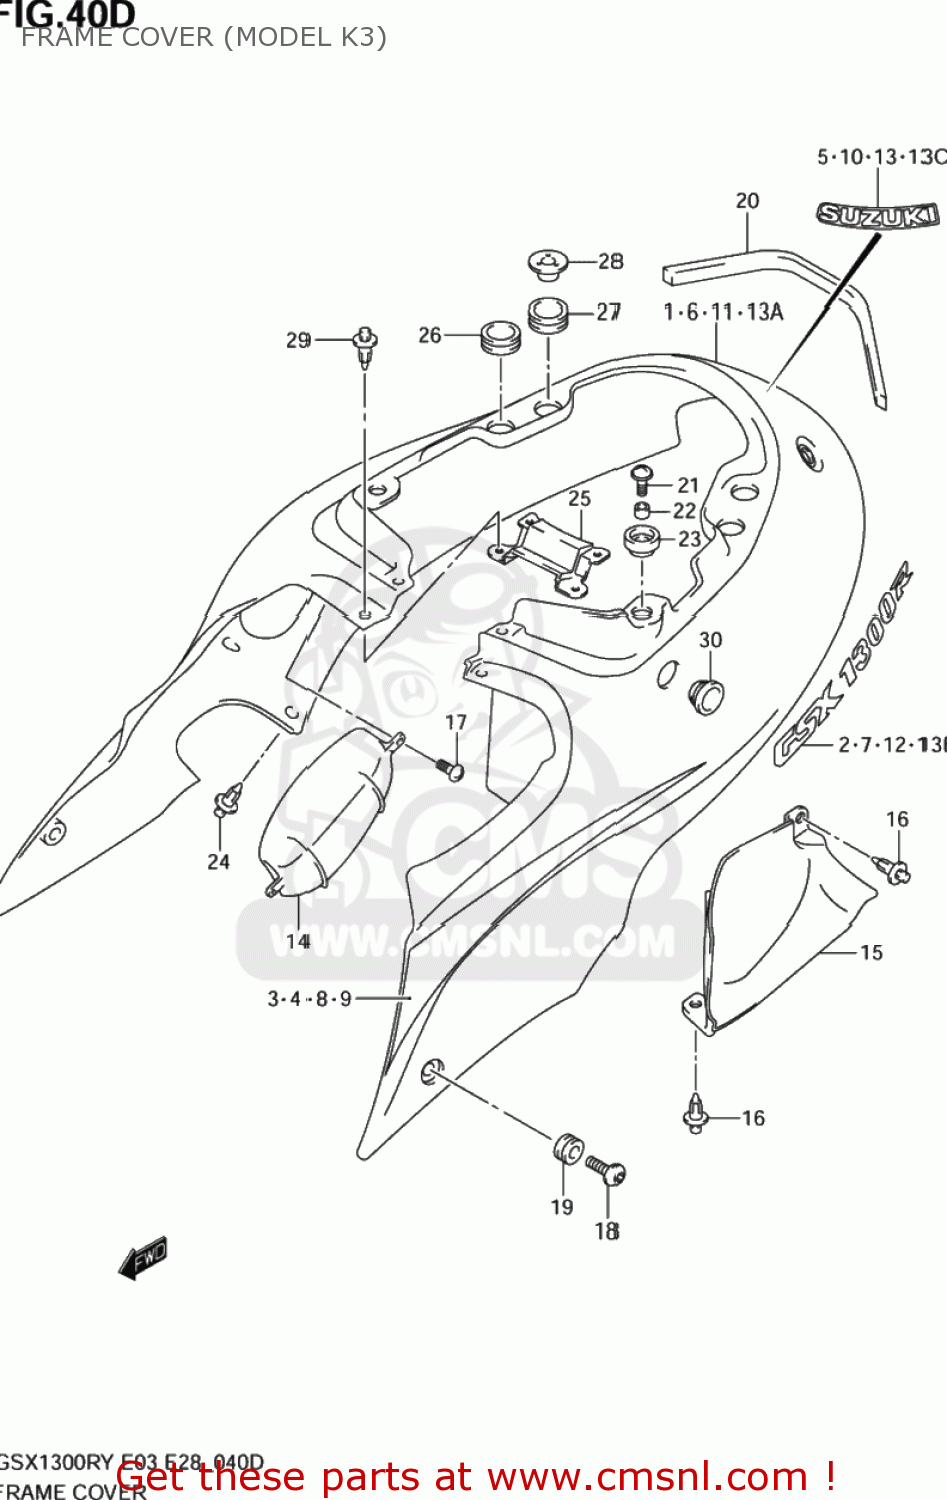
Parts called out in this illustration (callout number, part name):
1	COVER,FRAME(SILVER)
2	EMBLEM,FRAME COVER
3	TAPE,FRAME COVER,R(BLUE)
4	TAPE, LH (BLUE) FOR YD8
5	EMBLEM
6	COVER,FRAME(SILVER)
7	EMBLEM,FRAME COVER
8	TAPE,FRAME COVER,R(SILVER)
9	TAPE,FRAME COVER,L(SILVER)
10	EMBLEM,SUZUKI
11	COVER,FRAME(BLACK)
12	EMBLEM,FRAME COVER
13	EMBLEM,SUZUKI
13A	COVER,FRAME(ORANGE)
13B	EMBLEM,FRAME COVER
13C	EMBLEM,SUZUKI
14	CAP,FRAME COVER HOLE,R
15	CAP,FRAME COVER HOLE,L
16	CLIP(BLACK)
17	SCREW
18	SCREW(6X20)
19	CUSHION
20	CUSHION,FRAME COVER UPR
21	SCREW(6X20)
22	SPACER(6.5X10X11)
23	CUSHION
24	CLIP(BLACK)
25	COVER,FRAME CTR
26	CUSHION,FRAME COVER UPR RR
27	CUSHION,FRAME COVER UPR RR RR
28	WASHER,FRAME C
29	CLIP(BLACK)
30	CUSHION,FRAME COVER CTR
